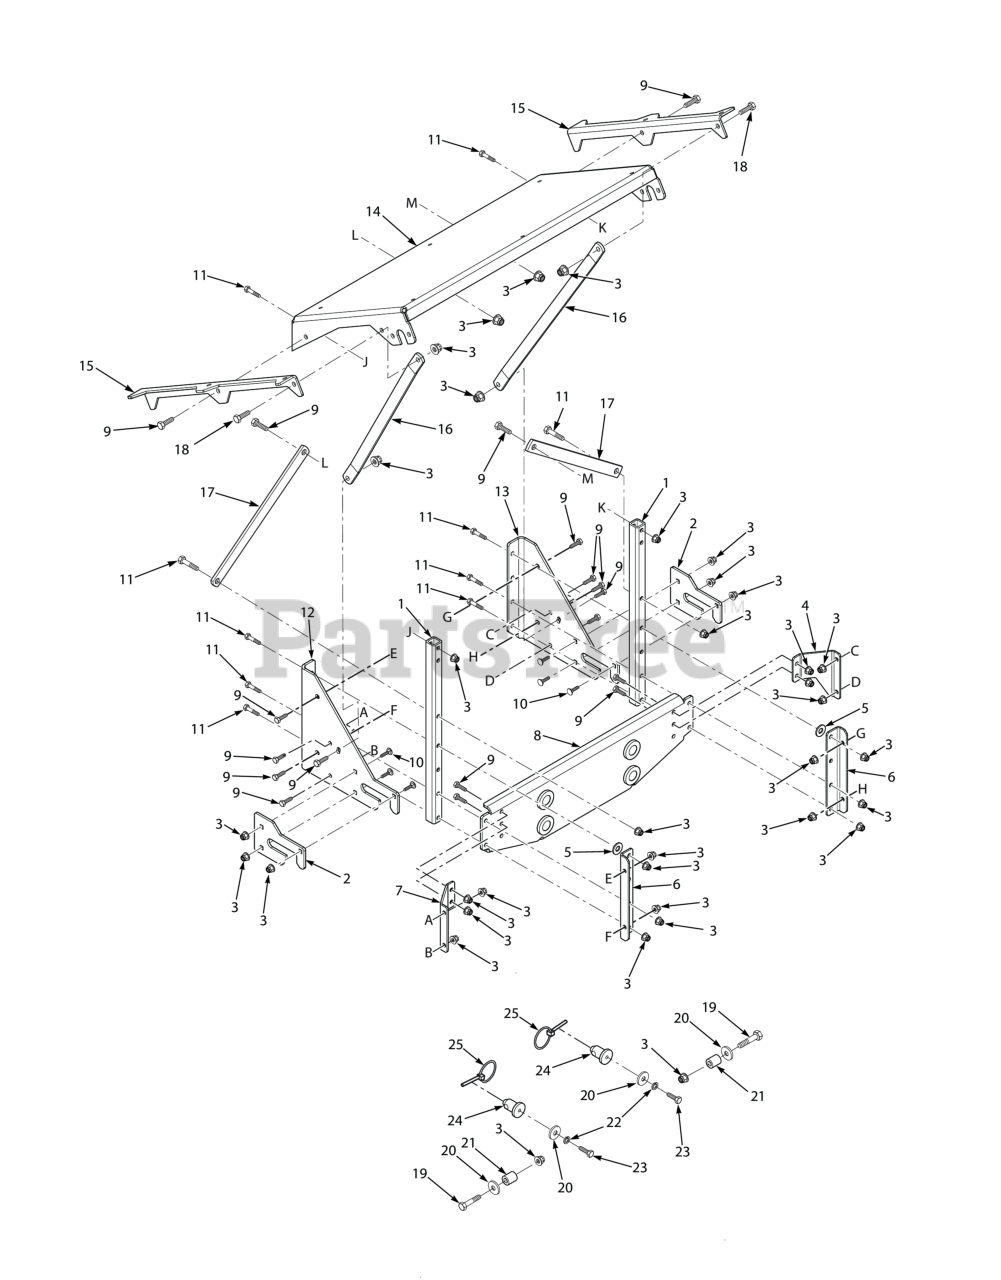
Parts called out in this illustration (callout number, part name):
1	Tube, Upright
2	Wear Plate, GC
3	Nut, Flange Elastic Stop Nut, 3/8-16
4	Angle Brace, LH GC
5	Flatwasher, 7/16-.469 x 1.75 x .25 (48, 52)
6	Mounting Bracket, GC Tube
7	Angle Brace, RH GC
8	Mounting Bracket Weldment
9	Bolt, Hex Head 3/8-16 x 1"
10	Carriage Bolt, 3/8-16 x 1.0"
11	Capscrew, Hex Head 3/8-16 x 2-1/2"
12	RH Mounting Bracket, GC
13	LH Mounting Bracket, GC
14	Support Frame, Hopper
15	Bracket, Hopper Support
16	Brace Stiffener, Short
17	Brace, Engine Mounting
18	Bolt, Hex Head, 3/8-16 x 1 Gr. 5
19	Bolt, Hex Head 3/8-16 x 2-1/4"
20	Flatwasher, 3/8-.406 x 1-1-1/2 x 7 Gauge
21	Spacer
22	Lockwasher, 3/8" Spring, Kawasaki FX / FT & FT-EFI / B&S 32BV
23	Bolt, Hex Head 3/8-16 x 1-1/4", Kawasaki FX / FT & FT-EFI
24	Pin, GC Locator
25	Quick Pin, 5/16" Dia.
